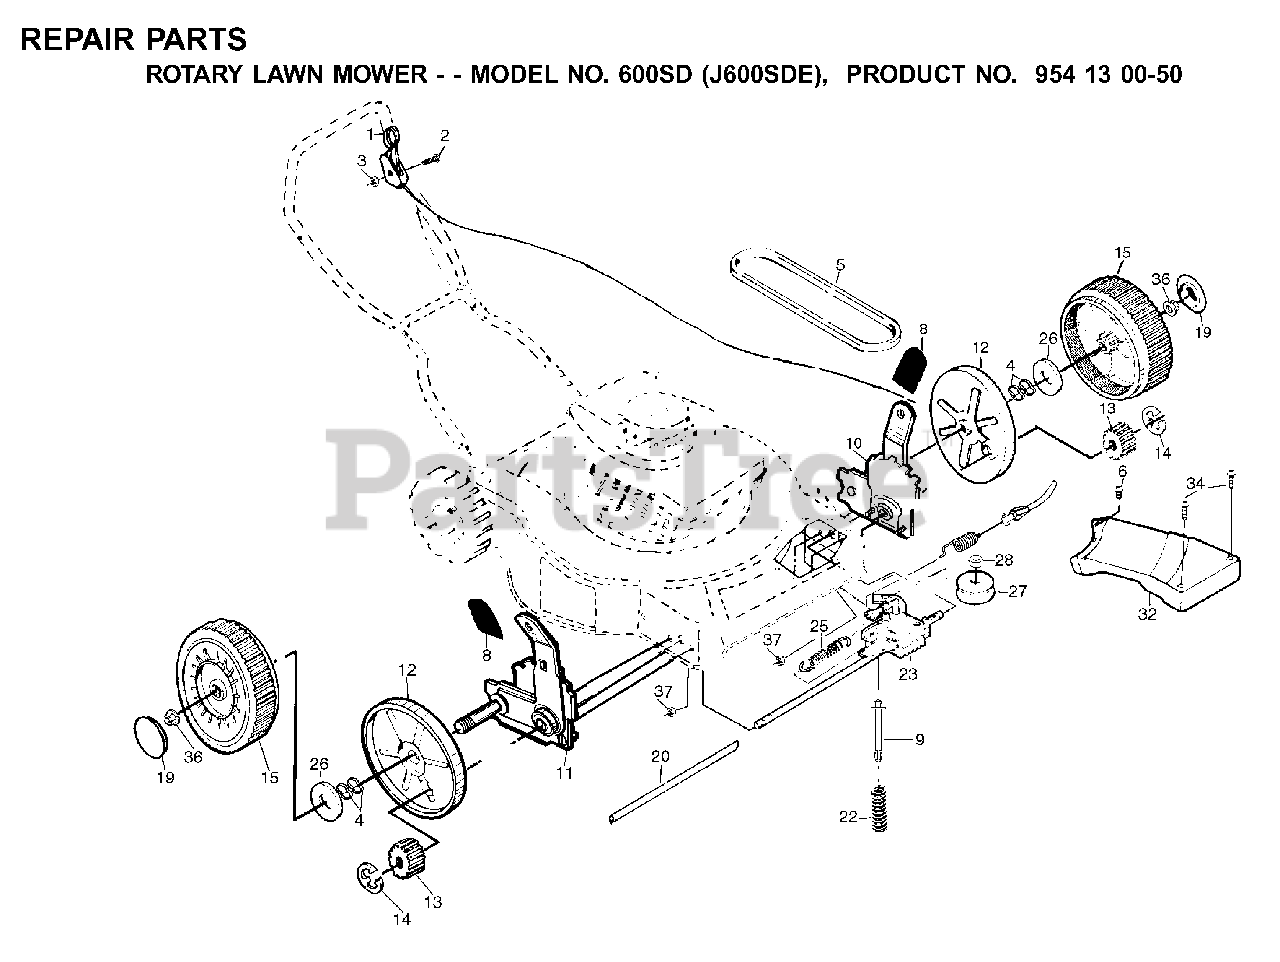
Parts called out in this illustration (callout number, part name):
1	CONTROL
4	WAVE WASHER
5	BELT THERM .32
6	TAPPING SCREW
8	SELECTOR KNOB
9	SPRING RETAINER
12	DUST SHROUD PM
13	PINION GEAR
14	E-RING 7/16 RE
15	WHEEL & TIRE 8 X 2
20	DRV SHAFT TUBE PM
22	SPRING.EXTENSION
23	GEAR CASE ASMBLY
26	WASHER FLUT
27	PULLEY
28	FLANGED LOCKNUT 3/8-16 ZINC
36	HEX FLANGE LOCKNT
37	NUT
